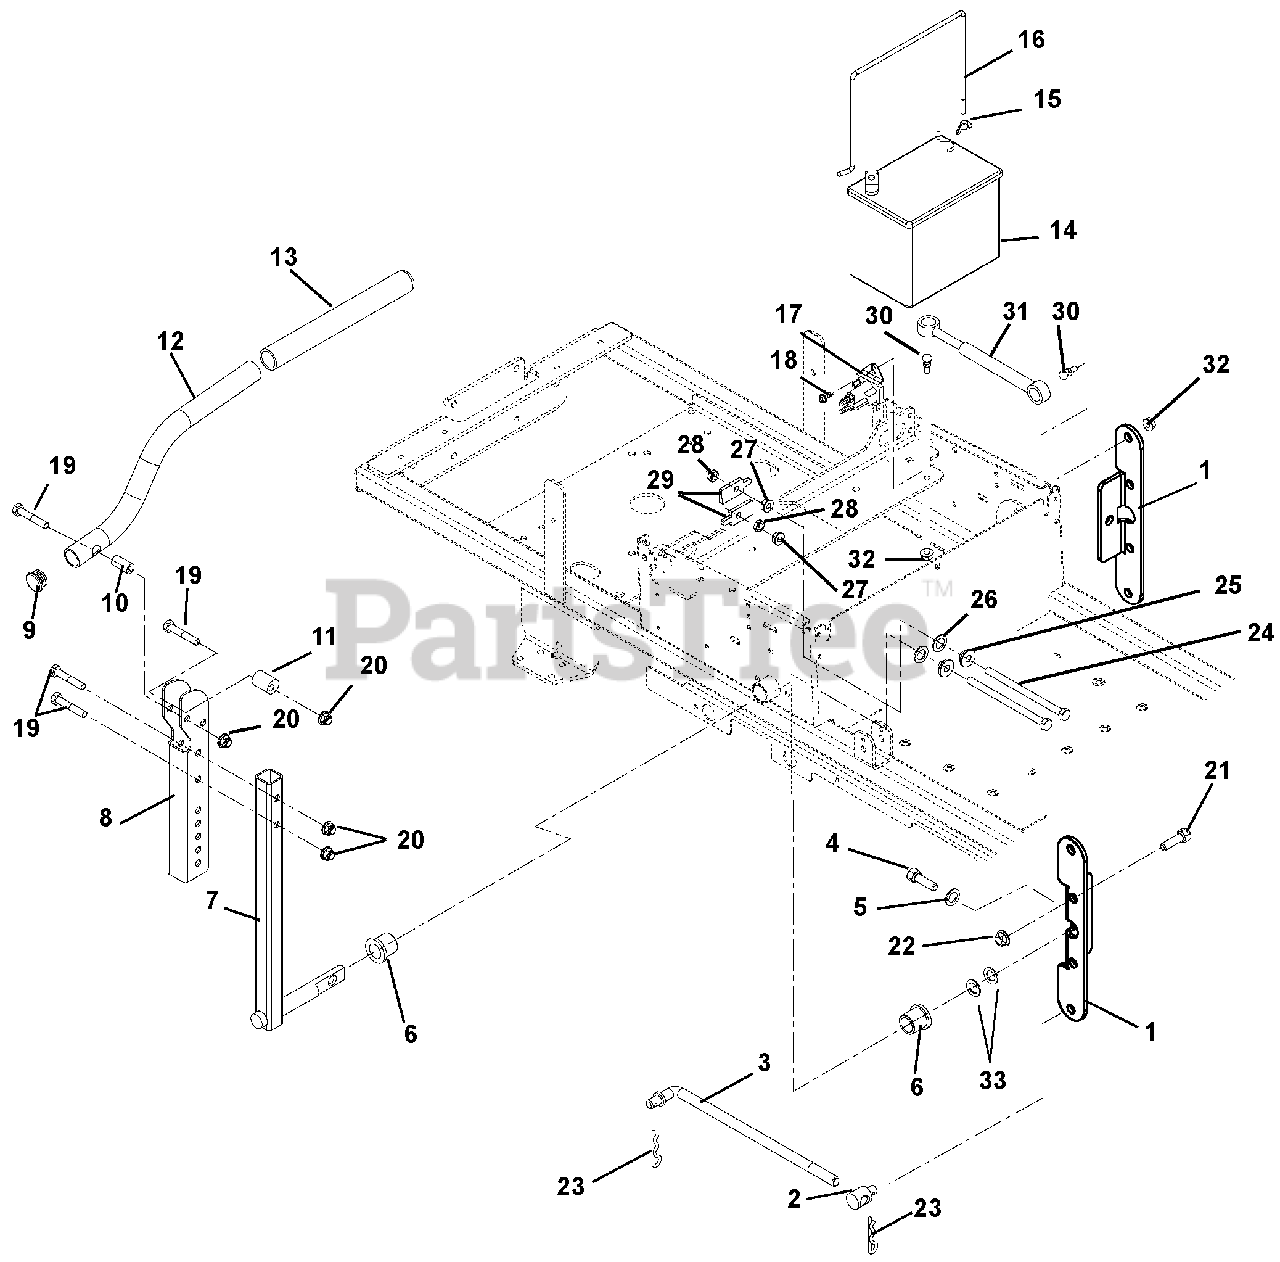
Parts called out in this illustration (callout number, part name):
1	LINK, CONTROL
2	PIVOT, ROD (TRUNNION ) .50
3	LINK,WIREFORM
4	BLT-HEX .38-16X1.0 GR8 YZ EP30
5	WSHR-FL-STL .390X1.5X.125 YWZC
6	BUSHING-1"X.75"X1"
7	WELDMENT, CONTROL ARM
8	CHANNEL, UPPER HANDLEBAR
9	CAPLUG, HANDLEBAR
10	BSHG, SPCR .330X.500X1.01 PM
11	BSHG,ECCEN .328X.750X1.01 PM
12	HANDLE BAR
13	GRIP - HANDLEBAR
15	NUT-LK WING .250-20 YWZC
16	BATTERY ROD
17	SOLENOID, HP RTV
18	@SCR-TAP .25-20X.37 HWH YWZ TR
19	@BLT-HEX .31-18X1.75 GR5 YWZC
20	@NUT-LK-NYL-FLG .31-18 YWZC
21	@BLT-HEX .38-16X1.25 GR5 YWZC
22	NUT-HEX-JAM .375-16 YWZC
23	PIN-HAIR INT .08X.18X1.18 YWZC
24	BLT-HEX,5/16-18X5 G2 HH YWZC
25	BSHG-FLG .32X.500X.344X.880
26	WSHR-FL-STL .52X.827X.062 YWZC
27	@NUT-SPNLK-FLG .312-18 YWZC
28	NUT- JAM .312-18 YWZC
29	STOP TAB
30	STUD- BALL
31	DAMPER, CONTROL
32	@NUT-LK-TOP-FLG .31-18 YWZC
33	WSHR-FL-STL .755X1.25X.125 YZ
